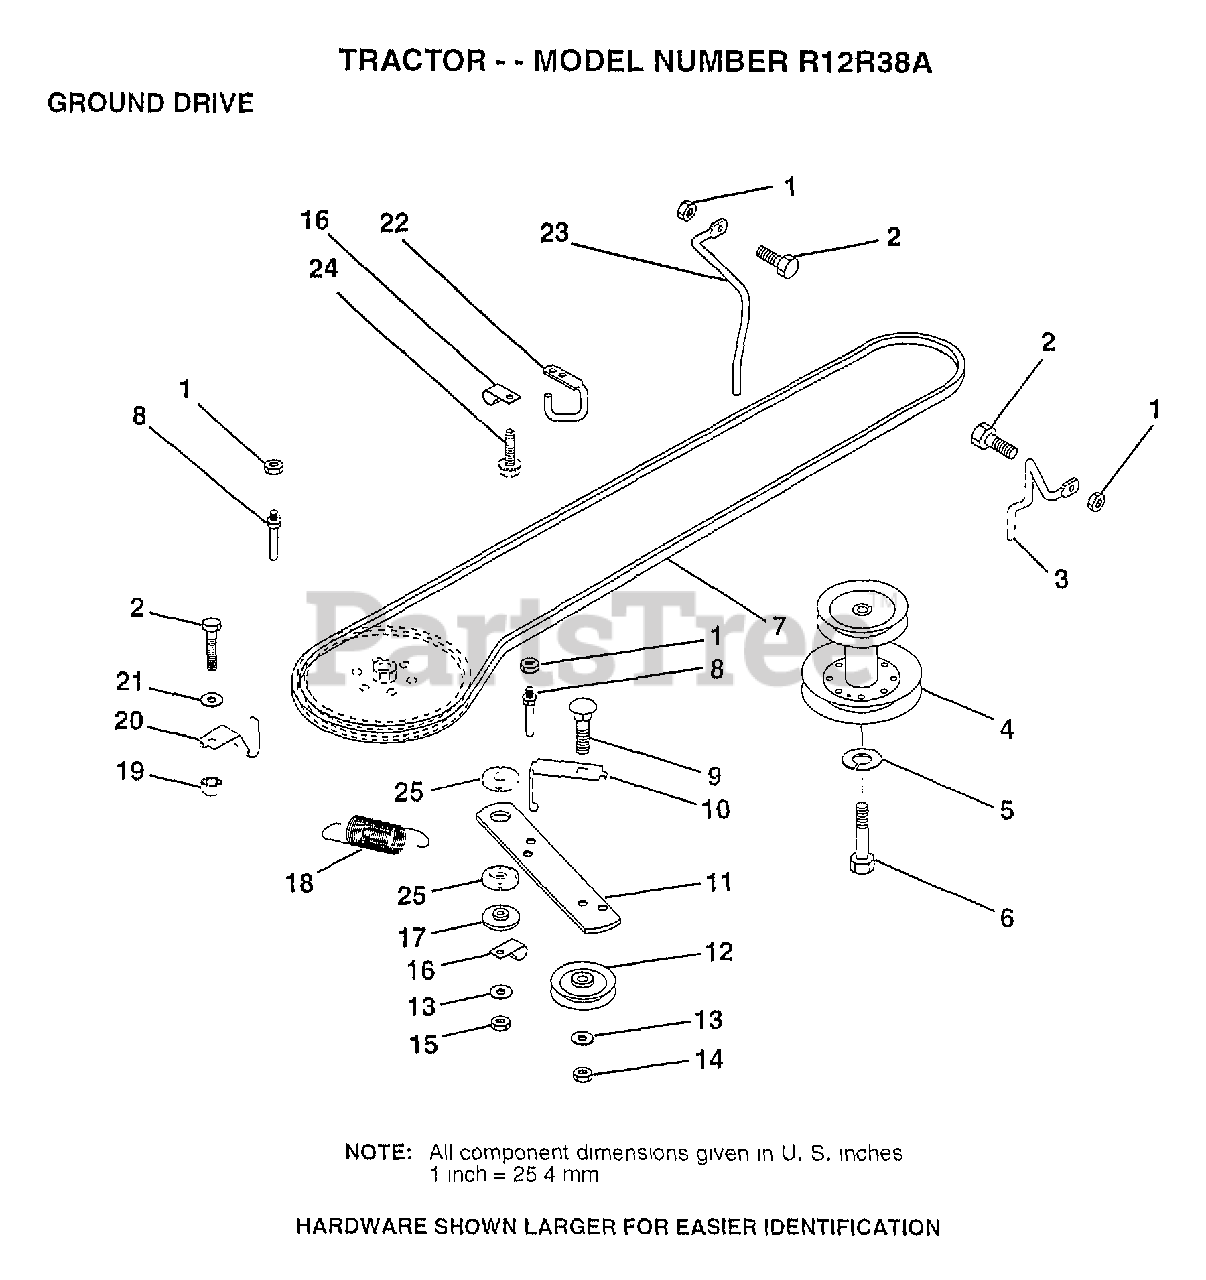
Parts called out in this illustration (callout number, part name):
2	BOLT
3	KEEPER.BELT.FRT.
4	PULLEY.ENGINE.LR
5	LOCKWASHER
6	HEX BOLT
7	V BELT
8	"KEEPER,DRIVE BELT"
9	BOLT
10	KEEPER BELT GROUND DRIVE CLUTCH
11	ARM-IDLER.DR.GRND
12	IDLER, FLAT
13	WASHER
14	LOCKNUT
15	NUT
16	"CLIP,INSULATOR"
17	SPACER
20	KEEPER.BELT.T/A
21	WASHER
22	"KEEPER,FRA DR BEL"
23	KEEPER.BELT.LH.FR
24	SCREW
25	BUSHING.NYLON
